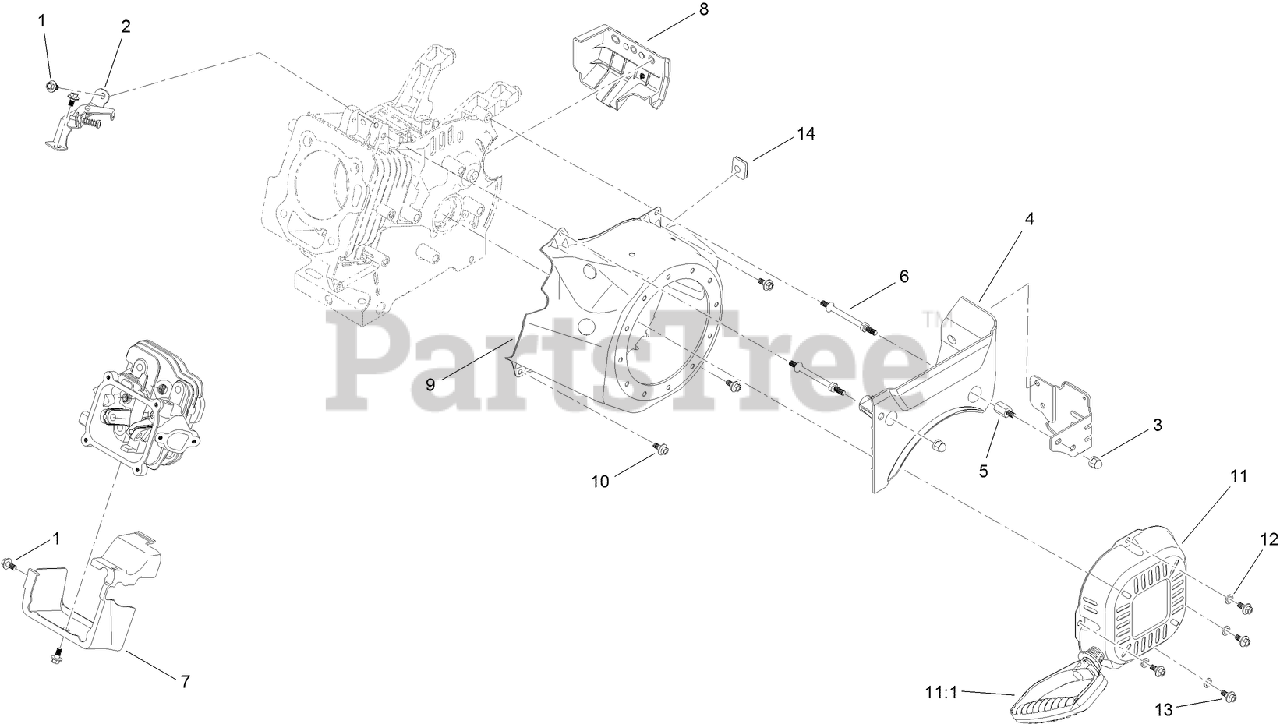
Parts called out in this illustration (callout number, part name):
1	SCREW-HHF
2	THROTTLE CONTROL ASM
3	NUT-ACORN
4	PANEL-FRONT
5	SPACER-STUD, THREADED
6	STUD-MOUNT
7	SHROUD-HEAD
8	PANEL-SIDE, ENGINE
9	SHROUD-FLYWHEEL
10	SCREW-HHF
11	RECOIL ASM
11:1	HANDLE-RECOIL
12	WASHER-PLAIN
13	SCREW-HHF
14	GROMMET-RUBBER
